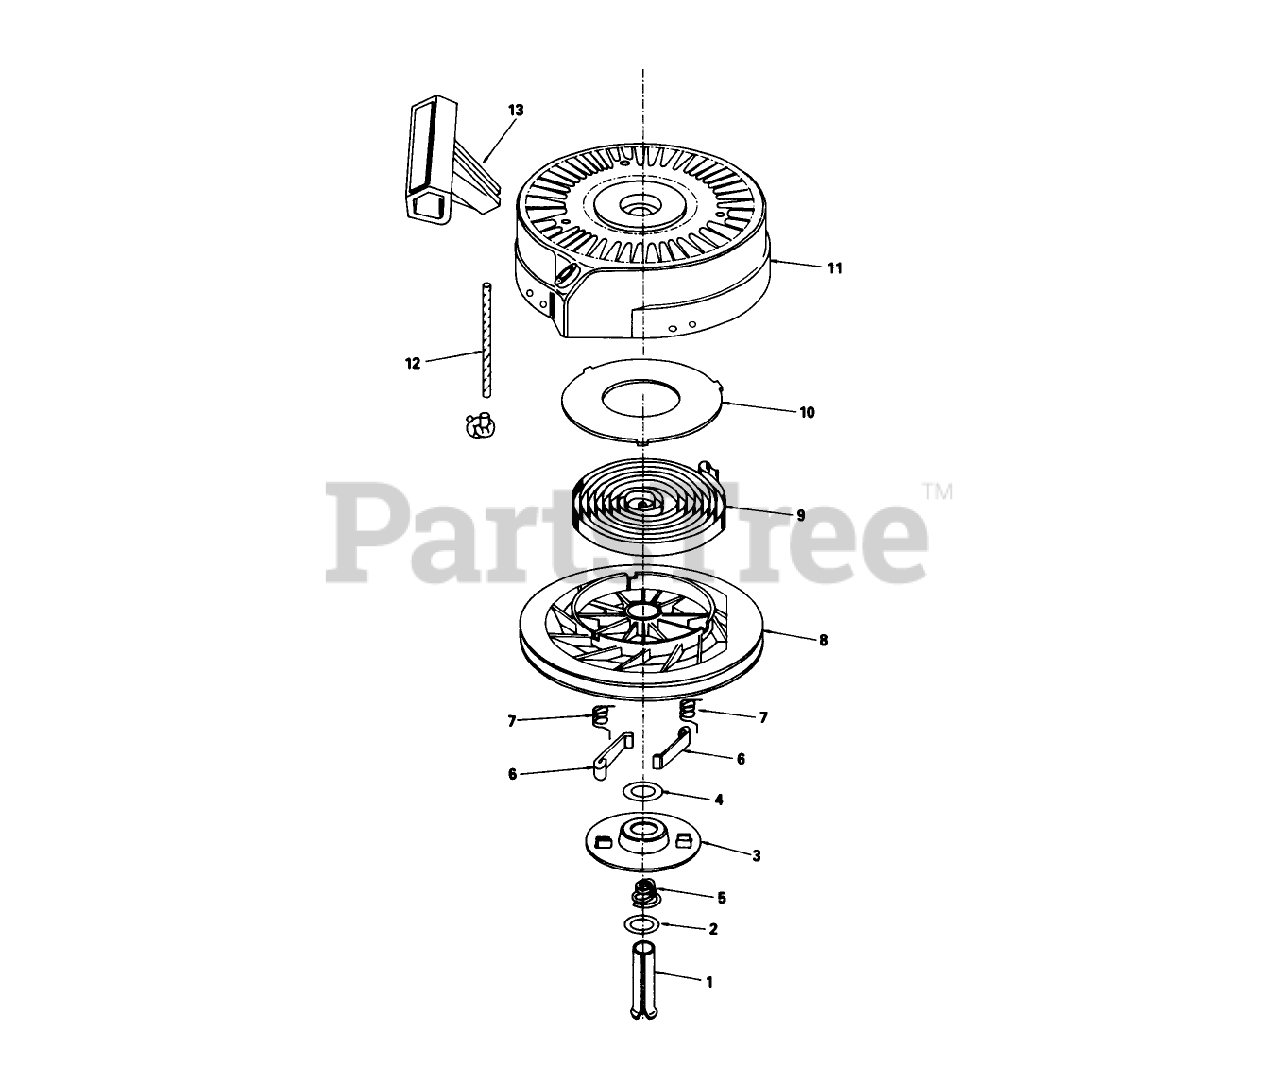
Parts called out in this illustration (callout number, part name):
1	Pin, Spring (Incl. Ref. #7)
2	Washer
3	Retainer
4	Washer
5	Brake Spring
6	Dog-Starter
7	Spring-Dog
8	Pulley
9	Rewind Spring
10	Cover-Spring
11	Housing-Starter
12	Rope-Starter (98 cut to length)
13	Handle-Starter
